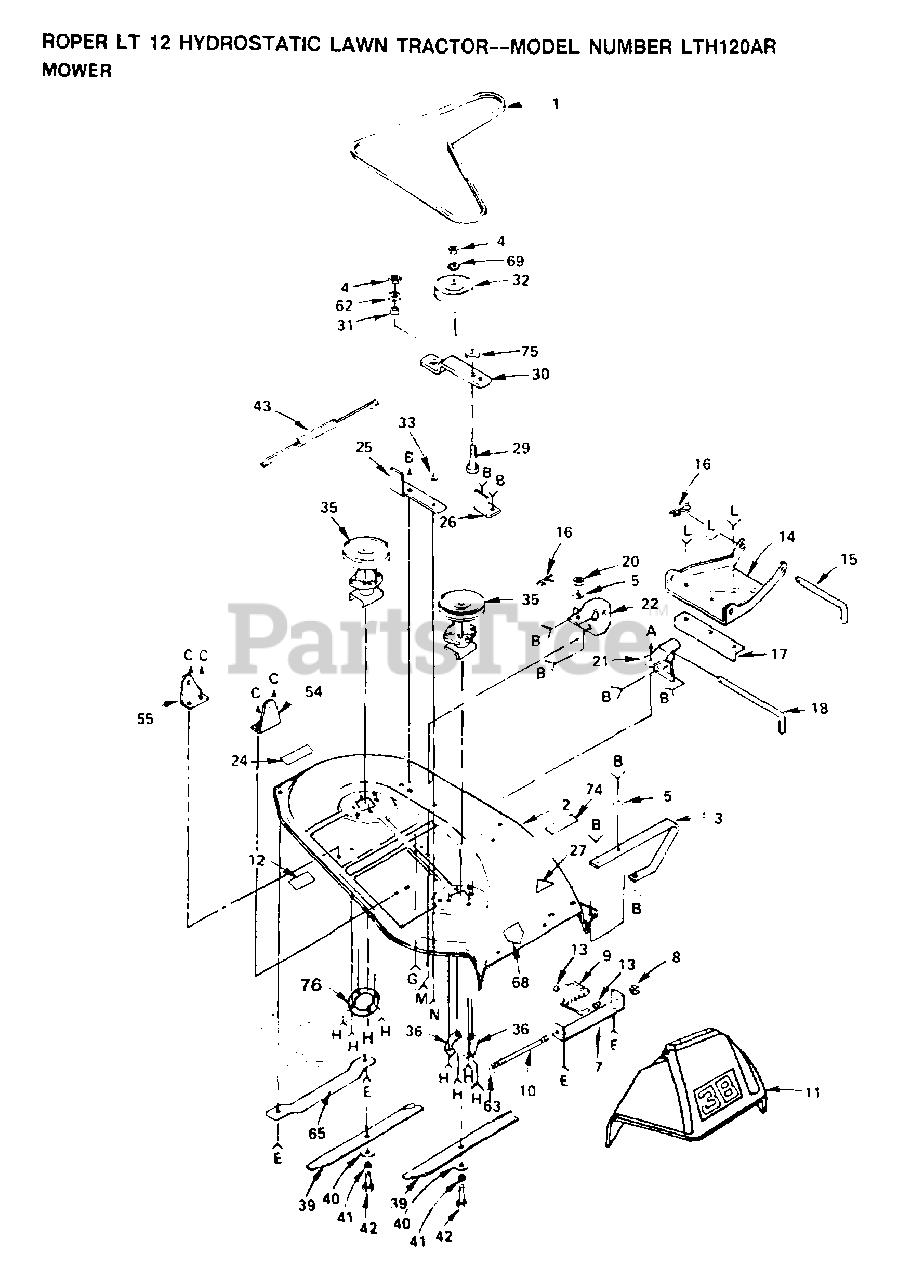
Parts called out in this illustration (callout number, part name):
1	BELT-V.79.1.MWR
5	WASHER M
8	NUT PUSH M
10	ROD-HINGE T
11	DEFLECTOR-SHLD T
13	CAP-SLEEVE LT
14	LINK.PARALLEL
15	"ROD, FRT. PARAL T"
16	SPRING.RETAINER
17	LINK STOP
18	HINGE PIN T
21	BRACKET RH LT
22	BRACKET LH T
24	DECAL INSTRUCTION CAUTION
25	SUPPORT ARM T
26	STOP T
31	SPACER RETAINER
32	IDLER-FLAT T
33	"WASHER, WEAR LT"
36	SUPPORT PLATE LT
40	WASHER
42	BOLT.3/8-24X1-1/2
43	"SPRING.EXT.8.5"""
54	"BRKT,SUSP RH T"
55	"BRKT,SUSP REAR LH"
63	WASHER
65	RUNNER-LH M
69	WASHER
74	DECAL.WARNING.T
75	WASHER
76	SUPPORT T
